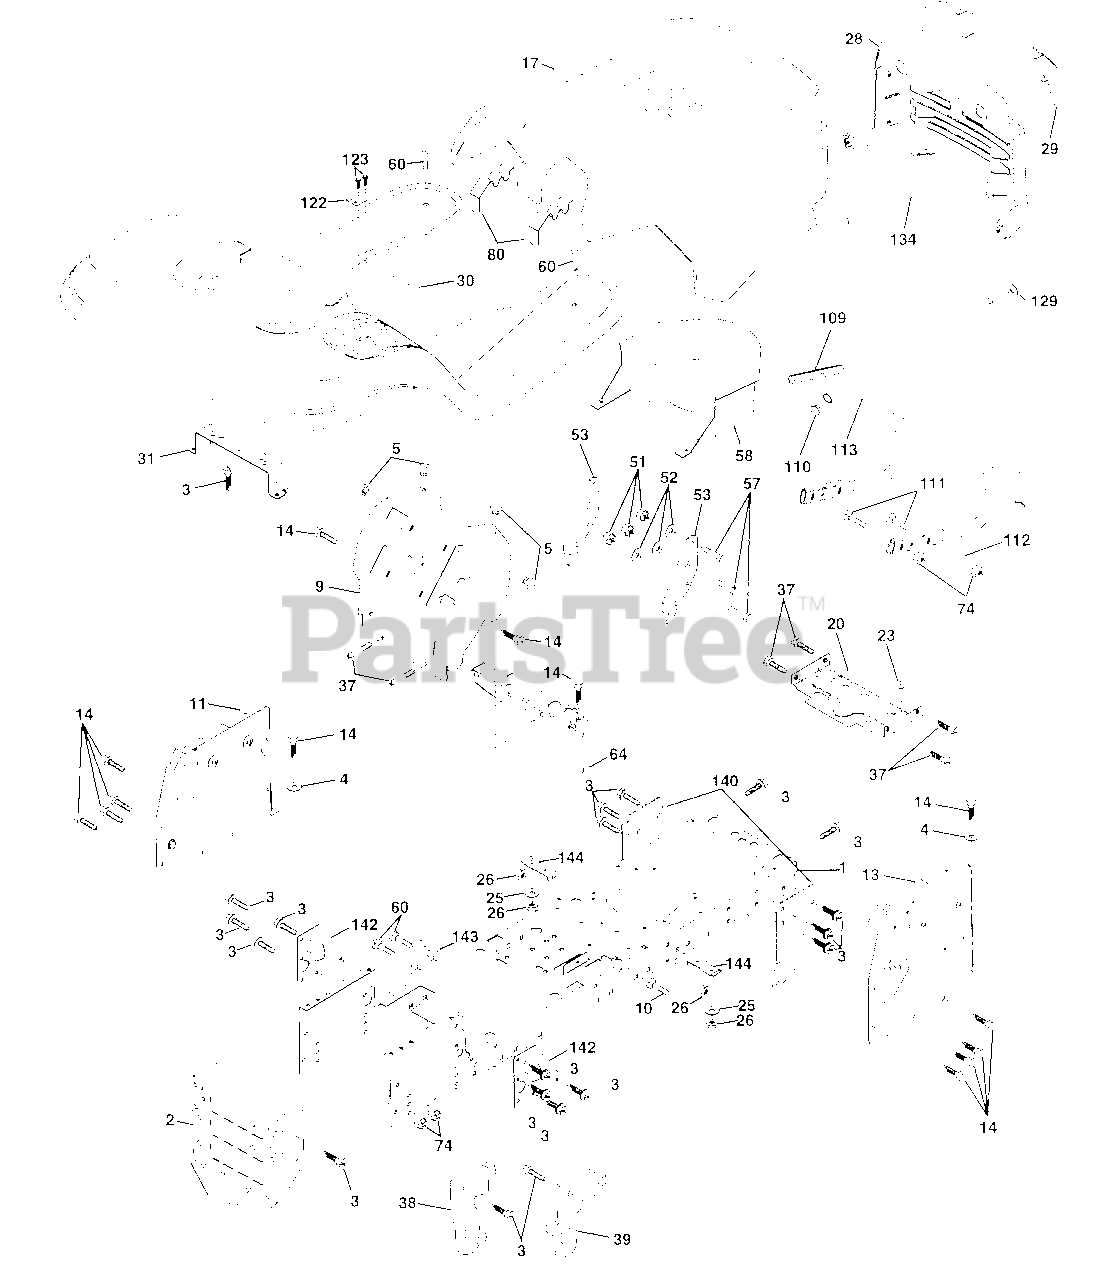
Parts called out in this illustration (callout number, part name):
1	Chassis Weldment
2	Drawbar, Stretch
3	Screw Thdrol 3/8-16 x 3/4 Ty-tt
4	Washer 13/32 x 3/4 x 16 Ga.
5	Bumper Hood/Dash
9	Dash Slkscr
10	Bolt Carriage 3/8-16 x 1
11	Panel Dash Lh
13	Panel Dash Rh
14	Screw Thdrol 3/8-16 x 1/2 Ty-tt
17	Hood LT/PL Husqvarna
20	Plate Mtg Battery Fuel Tank Fr
25	Washer 13/32 x 13/16 x 12 Ga
26	Nut Lock Hex W/Ins 3/8-16 Unc
28	Grille LT/PL Husqvarna
29	Lens LT/PL Husqvarna
30	Fender Footrest STLT Pnt
31	Bracket Support Fender
37	Screw Thdrol 6/16-18 x 1/2 TYT
38	Bracket, Asm. Pivot, L.H., Mower Rear
39	Bracket, Asm. Pivot, R.H., Mower Rear
51	Nut Lock Hex W/Ins 1/4-20
52	Washer 9/32 x 7/8 x 16 Ga.
53	Bracket Pnt. Pick off LT/PL Husqvarna
57	Bolt Hex 1/4-20 x 3/4
58	Air Duct Engine CV18
60	Bolt Rdhd Sqnk 3/8-16unc x 3/4
64	Dash Lower STLT
74	Nut Crownlock 3/8-16 UNC
80	Latch Hood Plm Husqvarna
109	Bracket Extension Bumper
110	Plug Plastic
111	Bolt Rdhd 3/8-16unc x 1-1/2
112	Washer 13/32 x 13/16 x 16 Ga.
113	Bumper Asm.
122	Bracket Shift STLT
129	Washer 9/32 x 5/8 x 16 Ga.
134	Rod Support Hood LT/PL Husq.
140	Bracket Chassis Front 7 Ga.
142	Plate Reinforcement STLT
143	Bracket Swaybar Chassis
144	Bracket Pnt Footrest STLT
146	Screw Torx Hd Thd 5/16-18 UN-2A
